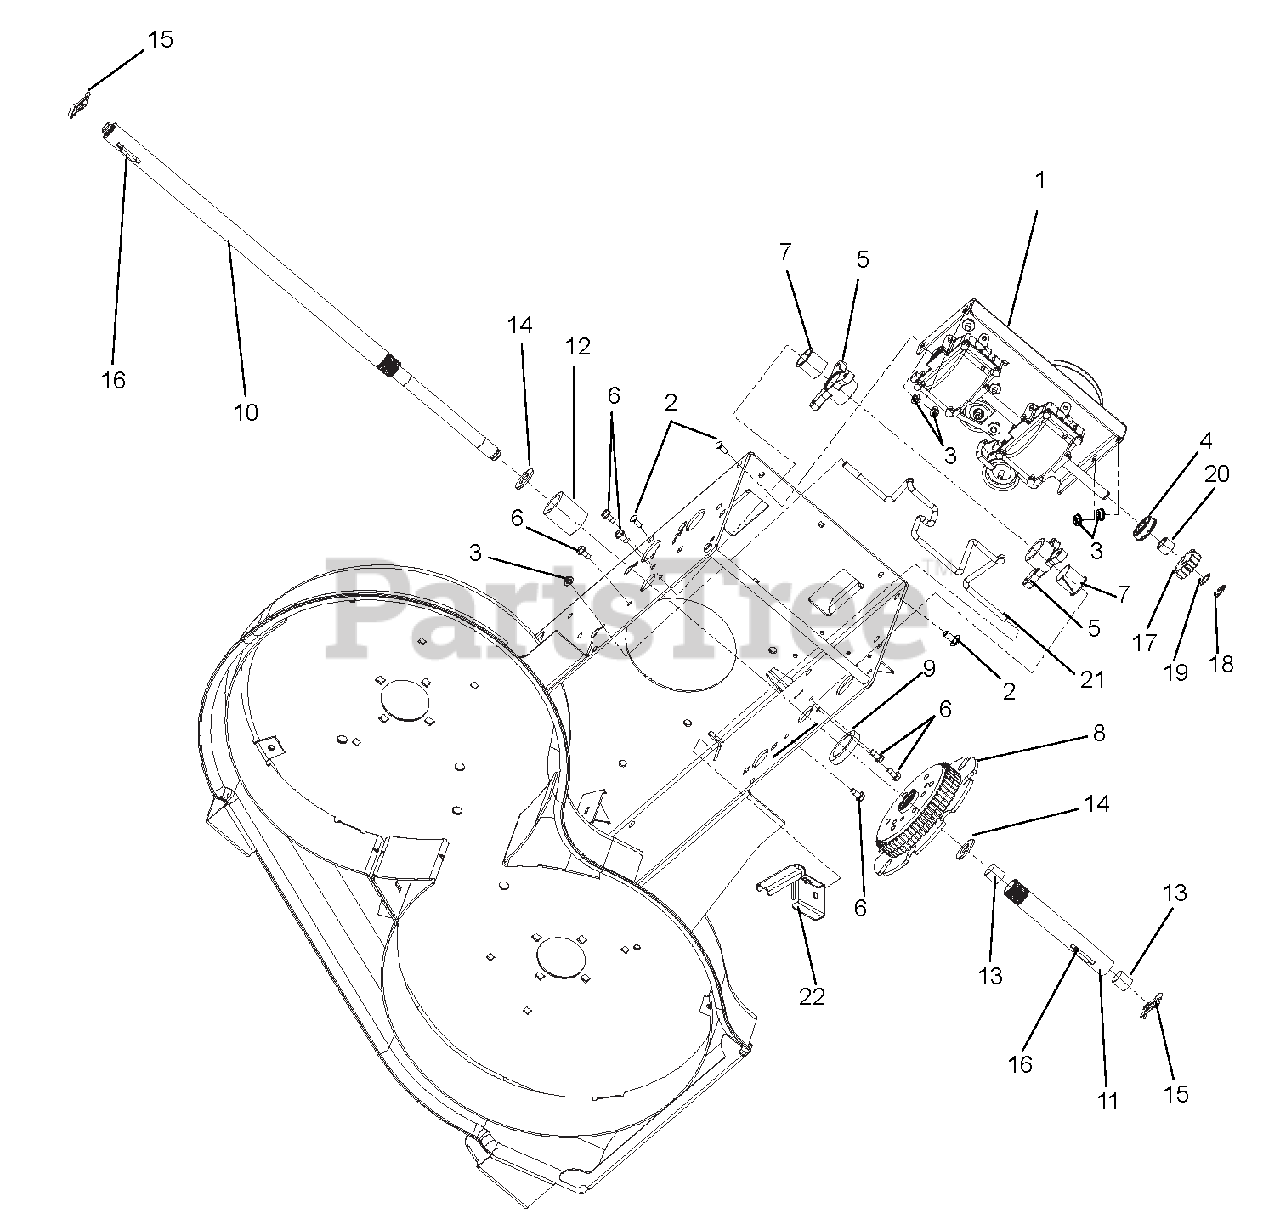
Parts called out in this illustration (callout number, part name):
1	KIT, WAW TRANSMISSION
2	@BLT-RDHDSQNK .31-18X.75 G5YZ
3	@NUT-LK-TOP-FLG .31-18 YWZC
4	BRG-BALL .50X1.38X.438 SEALED
5	BUSHING, RAKE SHAFT 1"
6	@SCR-TAP .25-20X.50 HWH TR YWZ
7	BSHG-FLG SPLIT NYLINER 1.0" HP
8	KIT, WAW DIFFERENTIAL
9	WSHR-FL-NY 1.42X2.03X.35
10	SHAFT-AXLE LONG
11	SHAFT-AXLE, SHORT
12	SPACER, 1.0X1.5X1.57
13	BSHG-SLV .706X.764X.75 BRZ
14	WSHR-FL-STL 1.010X1.505X.062YZ
15	CLIP, SNAP .625 DIA
16	KEY-RECT .25X.188X1.00
17	PINION, TRANSMISSION DRIVE
18	RG-RTNG-EXT .500X.042 (E)
19	WASHER, .500X.750X.020 THRUST
20	RETAINER, BEARING
21	BELT FINGER, WIREFORM
22	GUIDE, VERTICAL BELT
